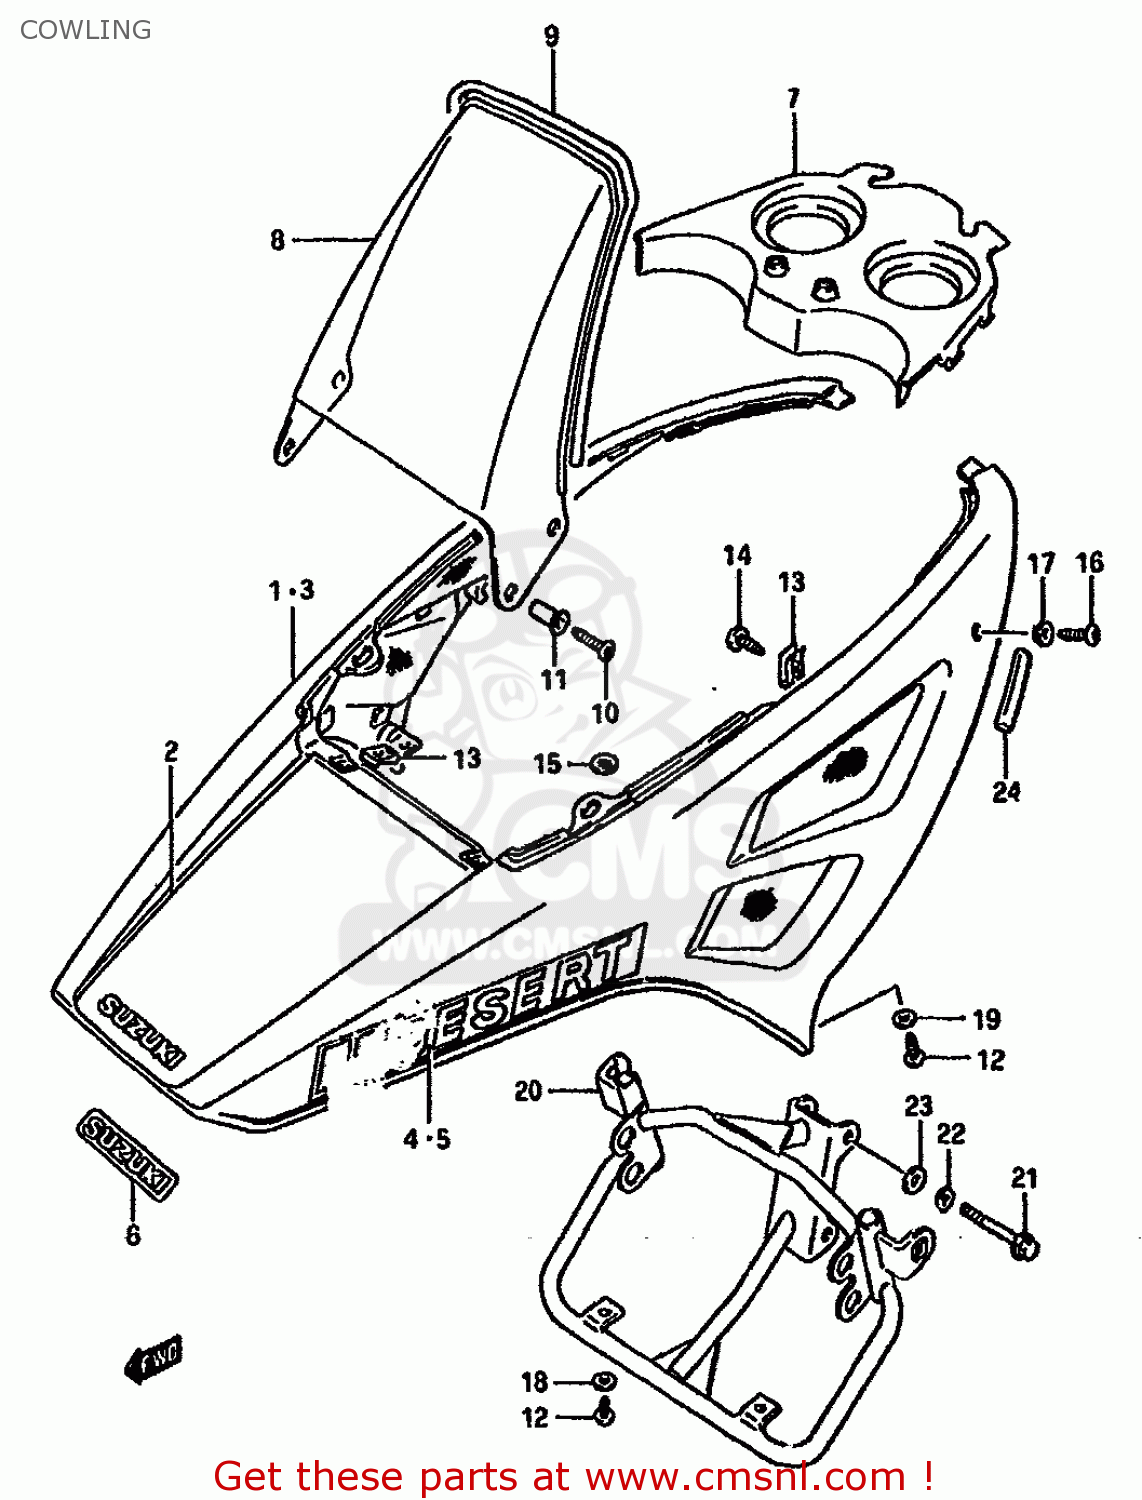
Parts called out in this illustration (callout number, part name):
1	BODY,COWLING (BLUE)
2	TAPE
3	BODY SET,COWLING
4	EMBLEM,SIDE RH
5	EMBLEM,SIDE LH
6	EMBLEM(WHITE)
7	BODY,CENTER (BLUE)
8	METER VISOR
9	MOLDING,VISOR
10	SCREW
11	NUT
12	SCREW
13	NUT
14	SCREW
15	NUT
16	SCREW
17	WASHER
18	WASHER (5.5X14X1.2)
19	WASHER (6.5X20X1.6)
20	BRACE,COWLING
21	BOLT
22	LOCK WASHER
23	WASHER
24	SEAL
